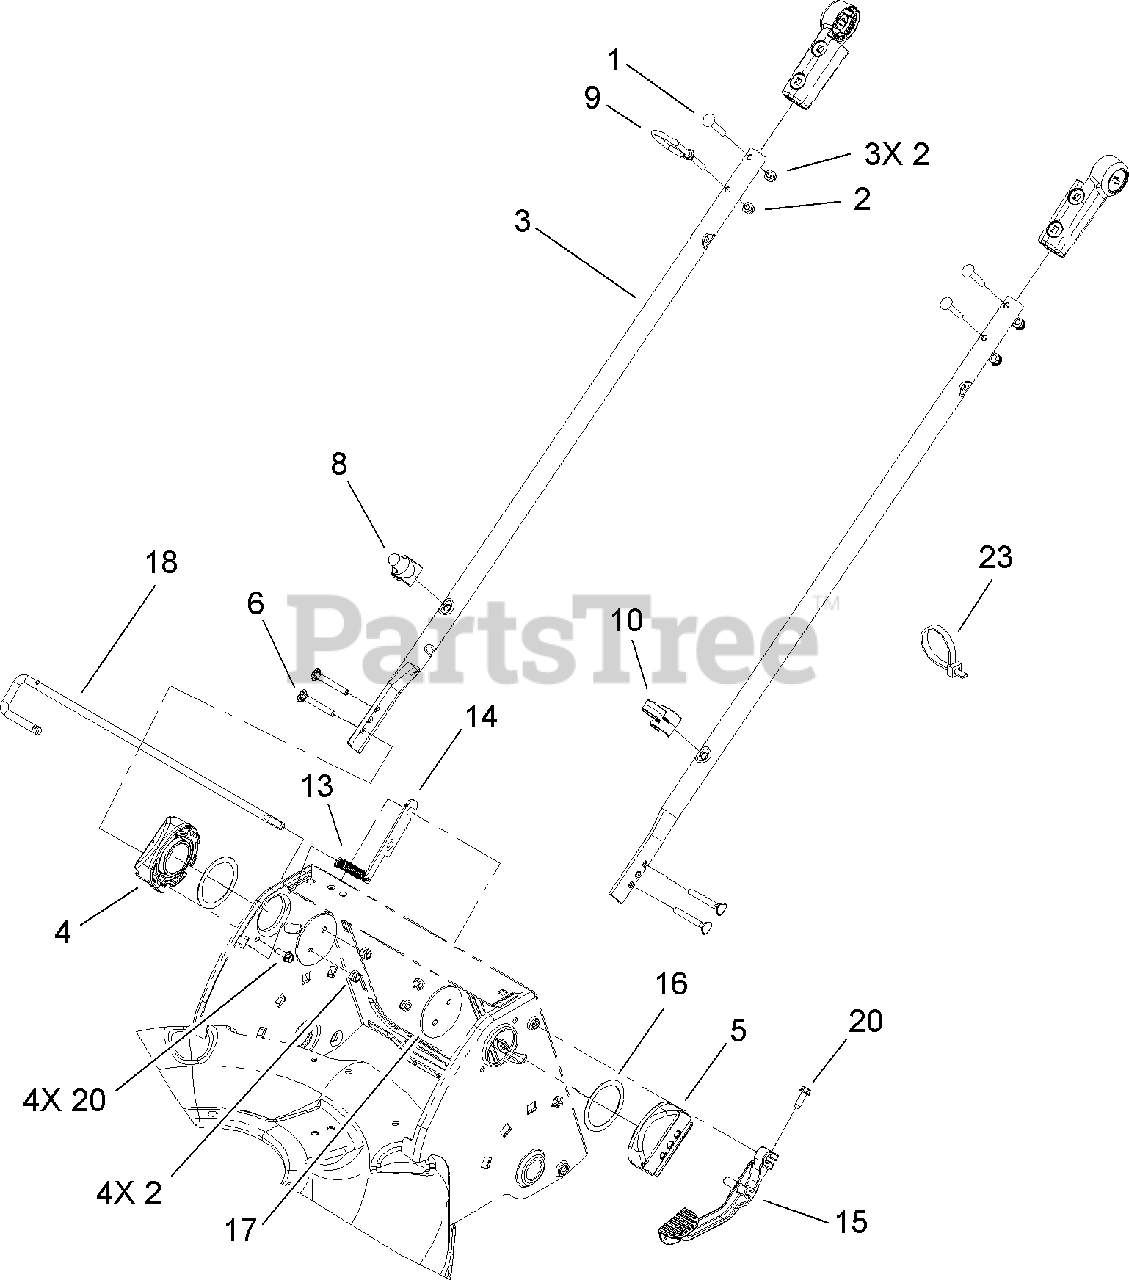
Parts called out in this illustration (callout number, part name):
1	SCREW-CARR
2	NUT-LOCK, NI
4	MOUNT-HANDLE, RH
5	MOUNT-HANDLE, LH
8	GUIDE-ROPE, LOWER
9	GUIDE-ROPE, UPPER
10	Guide-Cable
13	SPRING-EXTENSION
14	PLATE-RELEASE ROD
15	LEVER-RELEASE
16	WASHER-NYLON
18	HANDLE-ROD, RELEASE
20	SCREW-HWHTF
23	STRAP-TIE
